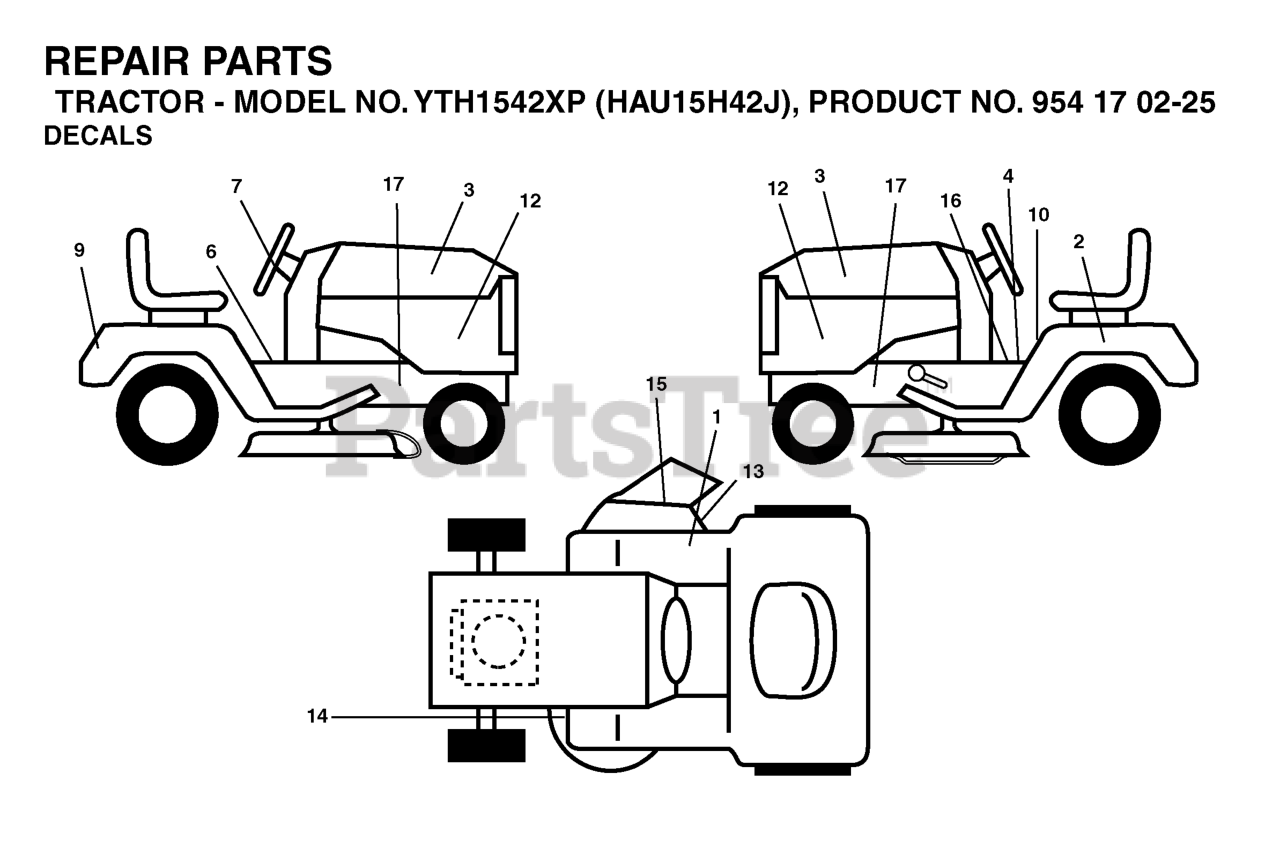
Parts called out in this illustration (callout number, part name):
1	DECAL
2	DECAL BTRY SYMBOLS
3	DECAL.HOOD.HUSQVARNA.INTERNATI
4	DECAL
6	DECAL PARK BRAKE
7	DECAL.STEERING.HUSQ.BLUE
10	DECAL READ OWNER'S MAN SYMS
13	DECAL.INTERNATIONL.CUTFINGER
14	DECAL V BELT SCHEMATIC
15	DECAL DECK "B" 42"
16	DECAL
